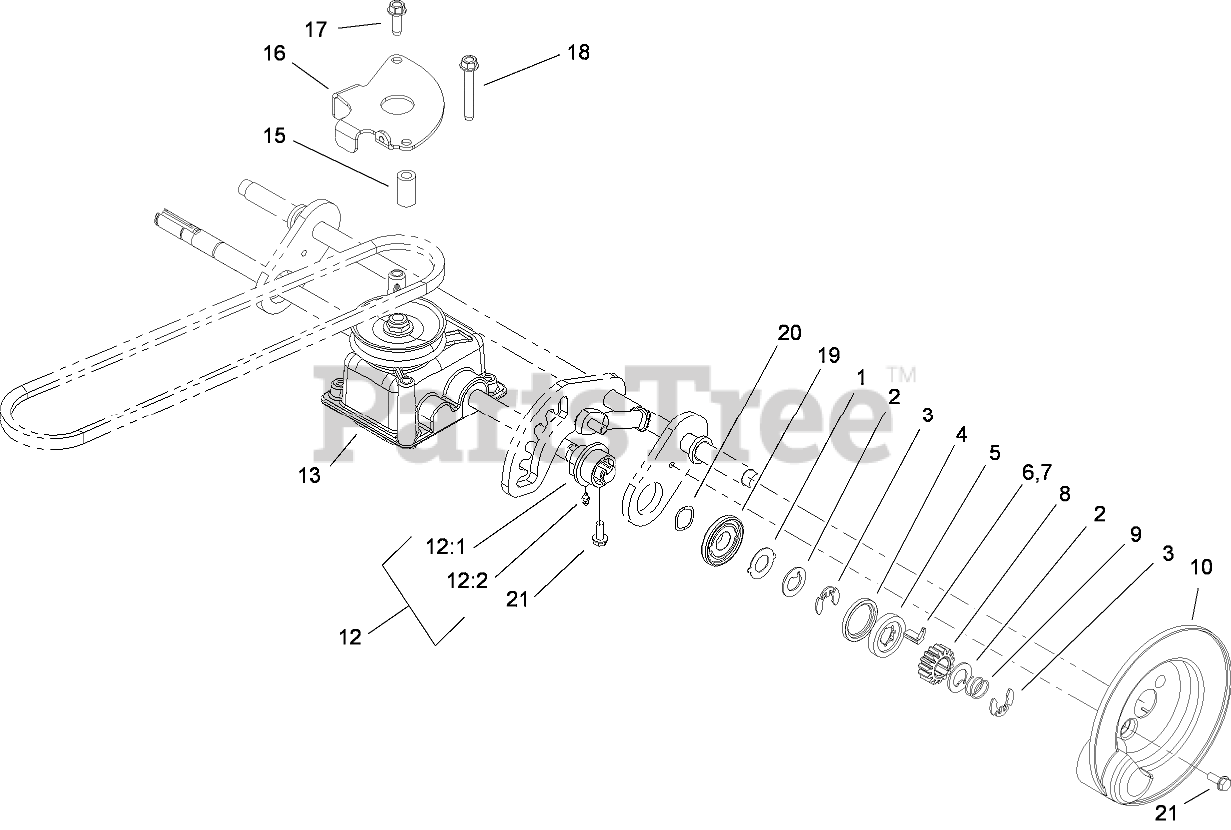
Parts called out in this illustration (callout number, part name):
1	WASHER-ARM, PIVOT
2	WASHER-THRUST, KEYED
3	RING-CLIP, LOCKING
4	RING-FRICTION
5	WASHER-CLUTCH
6	KEY-ROCKING, RH
7	KEY-ROCKING, LH
8	GEAR-PINION
9	SPRING-COMPRESSION
10	COVER-GEAR
12	BUSHING ASM
12:1	BUSHING
12:2	FITTING-GREASE
13	GEAR CASE ASM
15	BUSHING-PLATE, ACTUATOR
16	GUIDE-TRANSMISSION
17	SCREW-HWHTF
18	SCREW-HWHTF
19	RETAINER-RING
20	WASHER-WAVE
21	SCREW-TAPTITE
